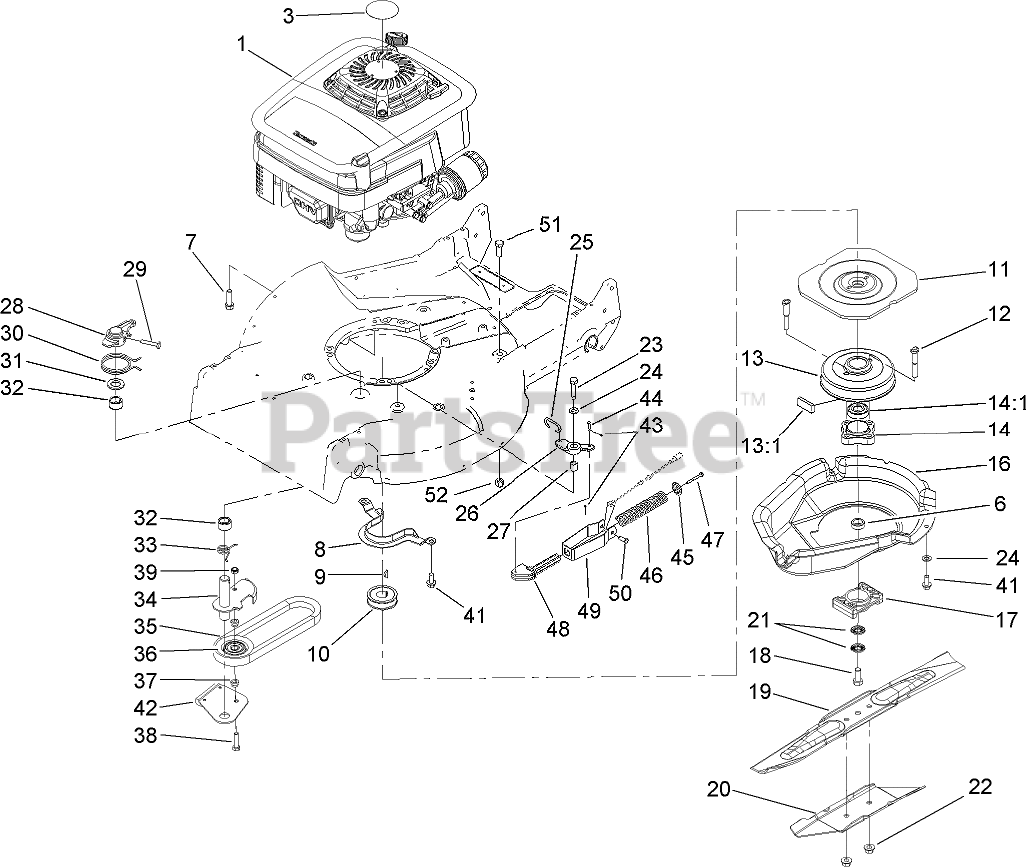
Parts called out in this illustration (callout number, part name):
1	ENGINE-KAWASAKI, FJ180V-AS30
3	DECAL-ENGINE, HONDA
6	SPACER-SHAFT, OUTPUT
7	SCREW-TAPTITE
8	BRACKET-GUIDE, BELT
9	KEY-WOODRUFF
10	PULLEY-DRIVER
11	FLYWHEEL-BBC
12	BOLT-BLADE
13	BRAKE DRUM ASM
13:1	DAMPENER-VIBRATION
14	HUB ASM
14:1	BEARING-BALL
16	SHIELD
17	SPACER-BLADE
18	SCREW-HH
19	BLADE-21 INCH
20	STIFFENER-BLADE
21	WASHER-SPRING
22	NUT-LOCK
23	SCREW-HH
24	WASHER-PLAIN
25	LINK-CONTROL
26	BELLCRANK
27	SLEEVE-BELLCRANK
28	LEVER
29	SCREW-HH
30	SPRING-TORSION
31	WASHER
32	BEARING
33	SPRING-TORSION
34	ARM-IDLER
35	V-BELT
36	PULLEY-IDLER
37	SPACER-PULLEY, IDLER
38	SCREW-HH
39	NUT-LOCK, NI
41	SCREW-HWHTF
42	BRAKE PLATE ASM
43	PIN-COTTER
44	PIN-SPRING
45	RETAINER-SPRING
46	SPRING
47	SCREW-HWHTF
48	GUIDE-SPRING
49	BRACKET-SPRING
50	PIN-CABLE
51	SCREW-HH
52	NUT-LOCK, NI
